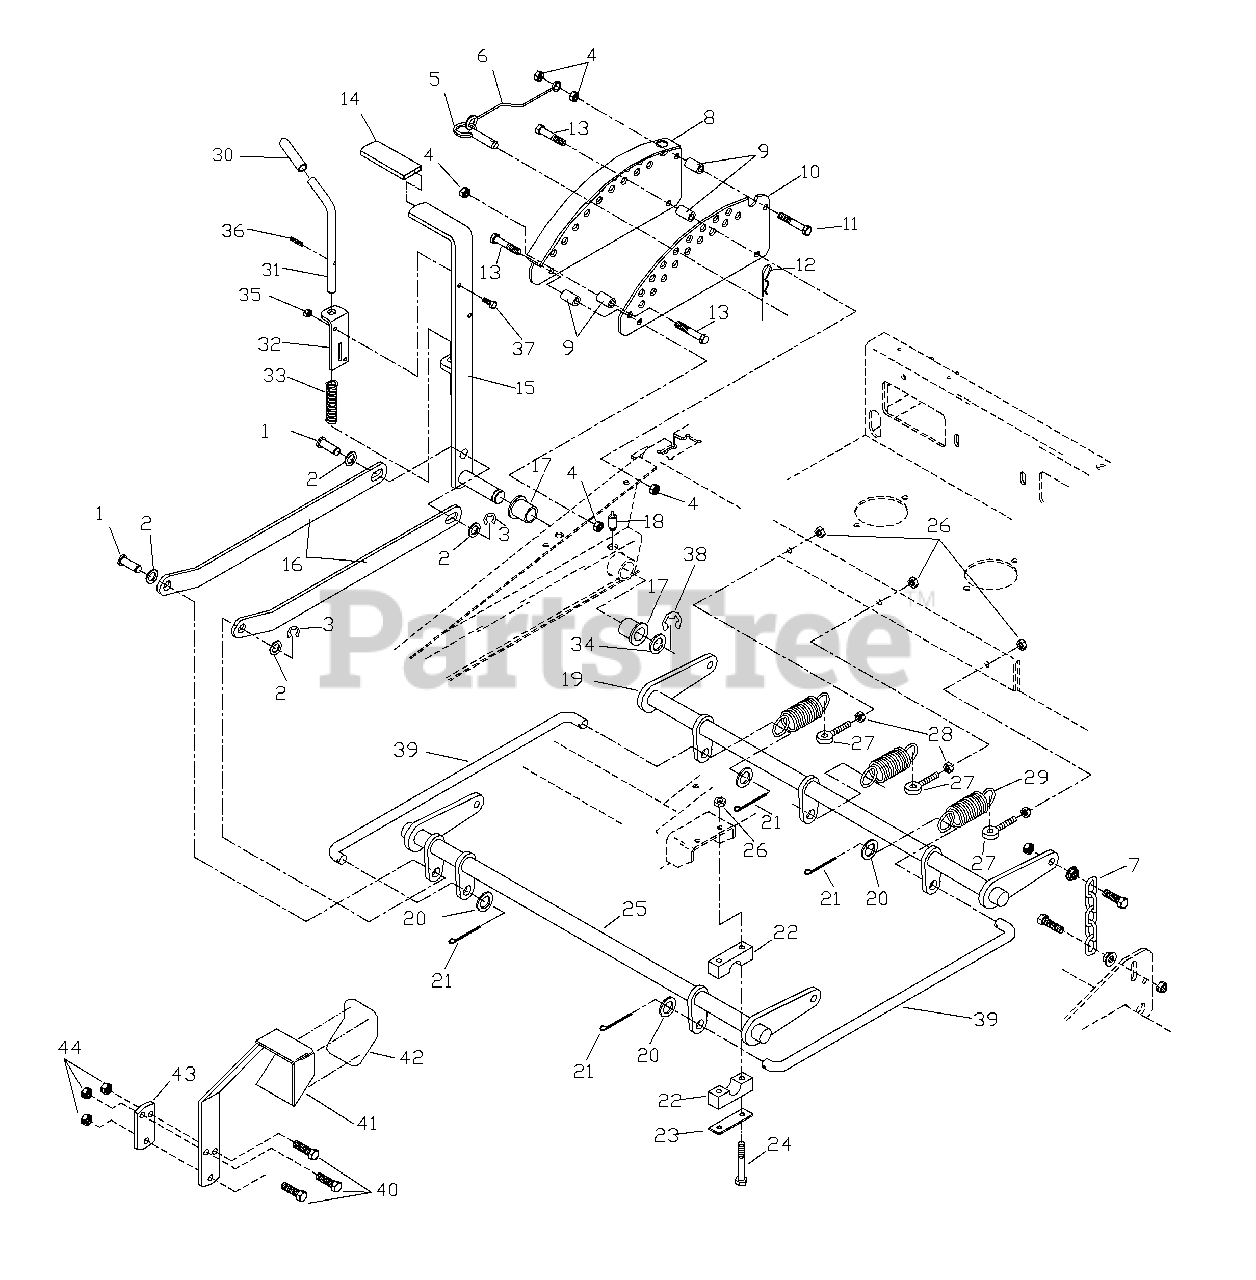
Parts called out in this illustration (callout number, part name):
1	CLEVIS PIN
2	MACH. BUSHING
3	5/8 E - RING
4	NUT 3/8C CTR. LOCK
7	LIFT CHAIN
8	ADJ. PLATE WLDMT.
9	DECK LIFT SPACER
10	ADJ. PLATE PAINTED
11	HCS 3/8C X 2.5
12	# 4 HAIR PIN
13	HCS 3/8C X 2.25
15	LEVER WLDMT.
16	LIFT LINKAGE
17	FLANGE BUSHING
18	ZERK - LONG
19	LIFT SHAFT
20	5/8 SAE WASHER
21	COTTER PIN
22	PILLOW BLOCK
23	SUPPORT PLATE
24	HCS 5/16C X 2.5
25	LIFT SHAFT, FRONT
26	.NUT 5/16C CTR. LOCK
28	5/16C WHIZ NUT
29	DECK LIFT SPRING
32	PIN MT.,UPPER
34	MACH. BUSHING
35	NUT 1/4C CTR. LOCK
36	3/16 X 1 ROLL PIN
37	HCS 1/4C X 3/4
38	7/8 E - RING
39	CONN. LINK
40	HCS 3/8 X 1.5
41	LIFT PEDAL
42	ANTI-SKID PAD
43	TIGHTING PLATE
44	NUT 3/8 NYLOC
